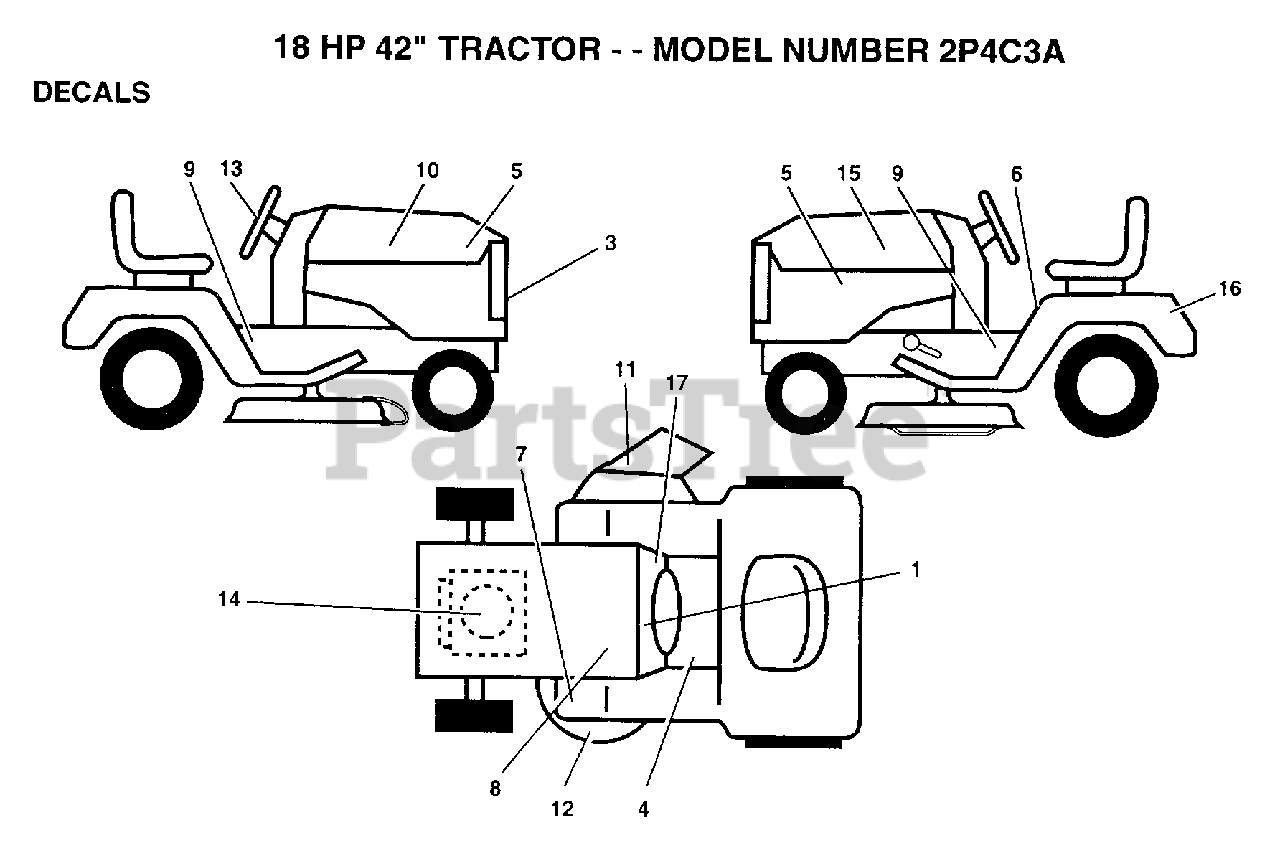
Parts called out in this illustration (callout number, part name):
3	GRILL DECAL
5	DECAL PANEL T
6	DECAL CAUTION
7	DECAL T
8	DECAL
9	CHASSIS DECAL
11	"DECAL, WARNING"
13	"DECAL,STR WHL"
14	DECAL.ENG.272757
16	FENDER DECAL
